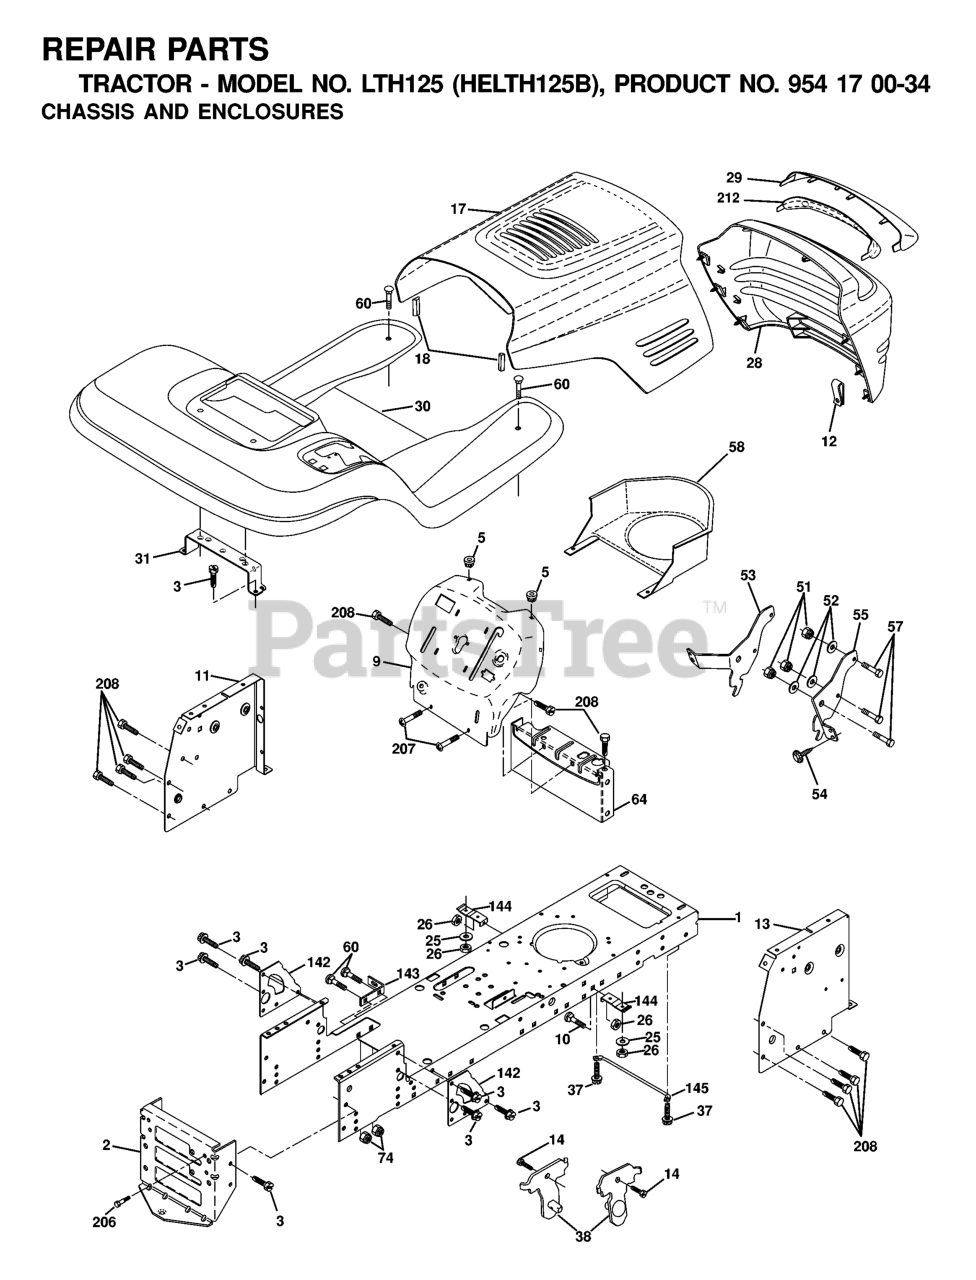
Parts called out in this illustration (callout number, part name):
1	CHASSIS STAMPING
2	DRAWBAR, 12GA
3	SCREW 3/8-16X3/4
5	BUMPER.RUBBER.HOOD
9	DASH
10	BOLT D
11	PANEL DASH LH
13	PANEL DASH RH
17	HOOD ASM.
18	BUMPER HOOD T
25	WASHER
26	NUT
28	LENS
29	LENS
30	FENDER FOOTREST
31	BRACKET.SUPPORT.FENDER
37	Screw 5/16-18 x 1/2 Hex, Self Tapping 5/16-18 x 1/2
38	BRACKET.ASM.PIVOT.MOWER.REAR
51	LOCKNUT.NYLOC.1/4-20
53	BRACKET.GRILLE.LH
54	SCREW.HEX.WS.HD.8-18 X 7/8
57	BOLT
58	AIR DUCT P/L/LT
60	Bolt - Rd. Hd. Sq. Neckiage 3/8 16 x 3/4
64	DASH LOWER
142	PLATE
143	BRACKET, SWAY BAR
144	BRACKET FOOTREST
145	ROD PIVOT CHASSIS/HOOD
206	SHOULDER BOLT 5/16-18TT
207	SCREW, 5/16-18 X 1/2
208	SCREW 3/8-16X1/2
212	REPL BY 532 1745-03
